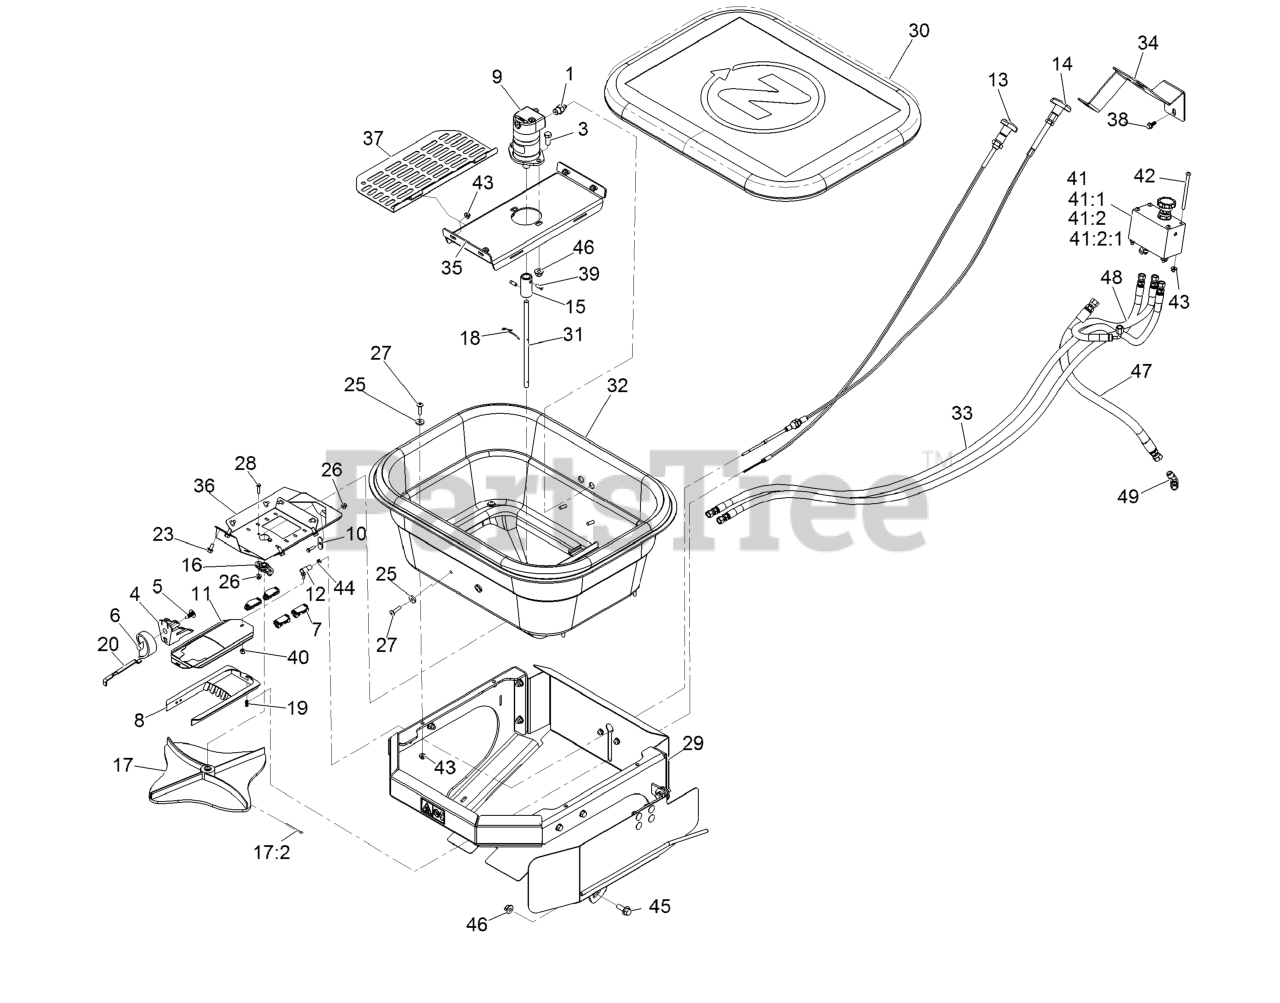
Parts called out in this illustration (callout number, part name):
3	SCREW-HH
4	MOUNT-DIAL
5	CLIP
6	DIAL
7	GUIDE-RATE, GATE
8	DIFFUSER
9	MOTOR-HYDRAULIC, SPREADER
10	RETAINER, CABLE
11	Slide-Door, Hopper
12	BALL JOINT-SS
13	CABLE-PUSH/PULL
14	CABLE-PUSH/PULL
15	COUPLER-SS
16	BEARING-FLANGE
17	SPINNER W/COTTER PIN
17:2	PIN-COTTER
18	WIRE-AGITATOR
19	RETAINER-CABLE, WIRE
20	LINKAGE-GATE, RATE
23	SCREW-HHF
26	Nut-Hex Flange
27	SCREW-PTH
28	SCREW-HH
29	Hopper ASM
30	COVER-HOPPER, SMALL
31	SHAFT, HOPPER, 120
32	120 LBS HOPPER\N05-296-22
33	HOSE ASM-HYD HP
34	Bracket-Hopper Cable
35	PAN, HOPPER, 120
36	BASE PLATE, HOPPER, 120
37	SCREEN, HOPPER, 120
38	Screw-HHF 1/4-20 X 5/8
39	Screw-SQH
40	Nut,NYL Lock,#10-32,ST/ST 18-8
41	Manifold-Flow Control, Hopper
41:2	FITTING-ELBOW, 45 DEG
41:2:1	O-RING
42	Screw-HSBH
43	Nut-Hex Flange
44	Nut,Hex Jam Mch Scr,10-32,Sst
45	SCREW-HHF
46	Nut-Hex Flange
47	HOSE ASM-HYD HP
48	HOSE ASM
49	FITTING-90 SWIVEL
